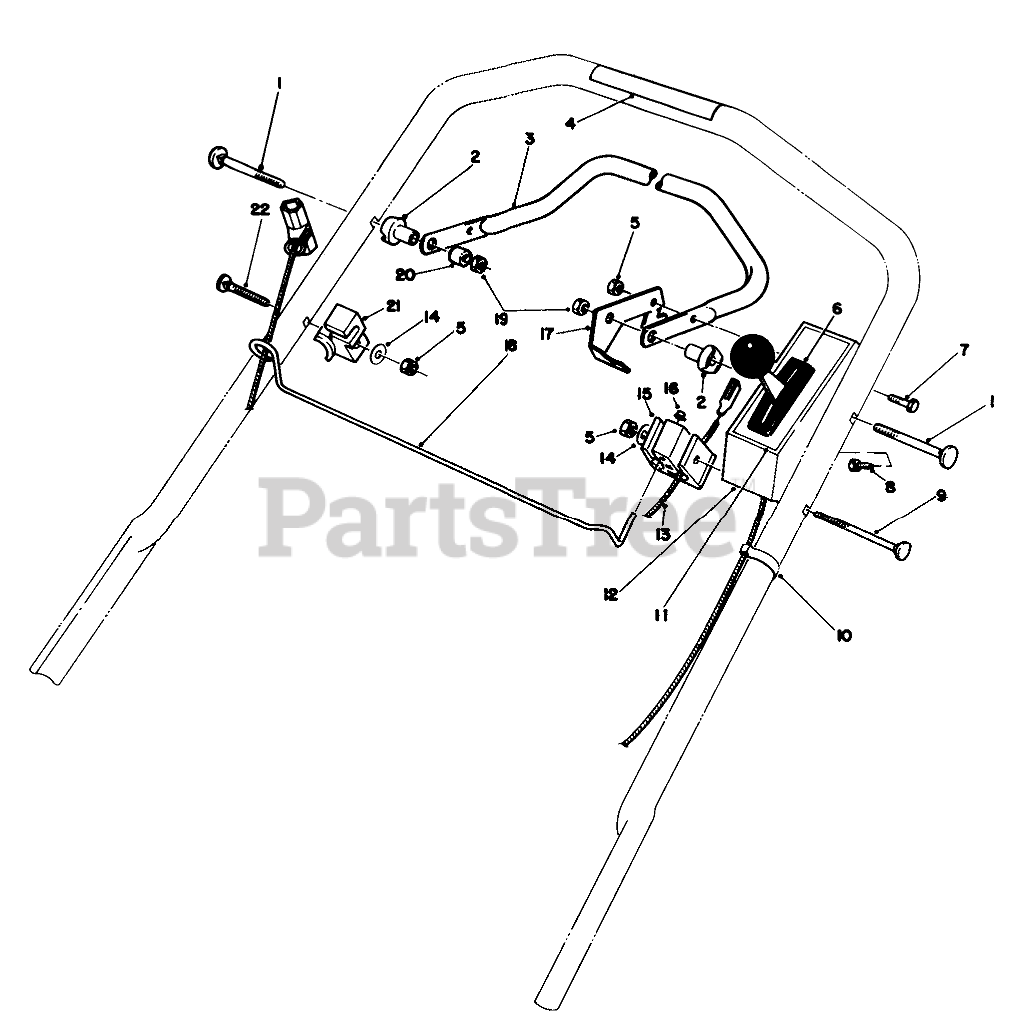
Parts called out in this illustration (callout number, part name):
1	5/16-18 X 2 HNDLE SCREW
2	SPACER-SUPPORT
3	Bar-Control
4	DANGER DECAL
5	NUT-LOCK, NI
6	SERVICE THROTTLE CONTRO
7	SCREW-HH
8	SCREW-HWHTF
9	HANDLE SCREW
10	BOWDEN CLIP
11	Decal-Control Cover
12	CONTROL COVER
13	BRAKE CABLE
14	WASHER-FLAT
15	SUPPORT-CABLE
16	NUT-SPEED
17	Lever-Control
18	ROPE ROD PLATED
19	NUT-LOCK, NI
20	SPACER-NYLON
21	ROD CATCH
22	SCREW-HANDLE
